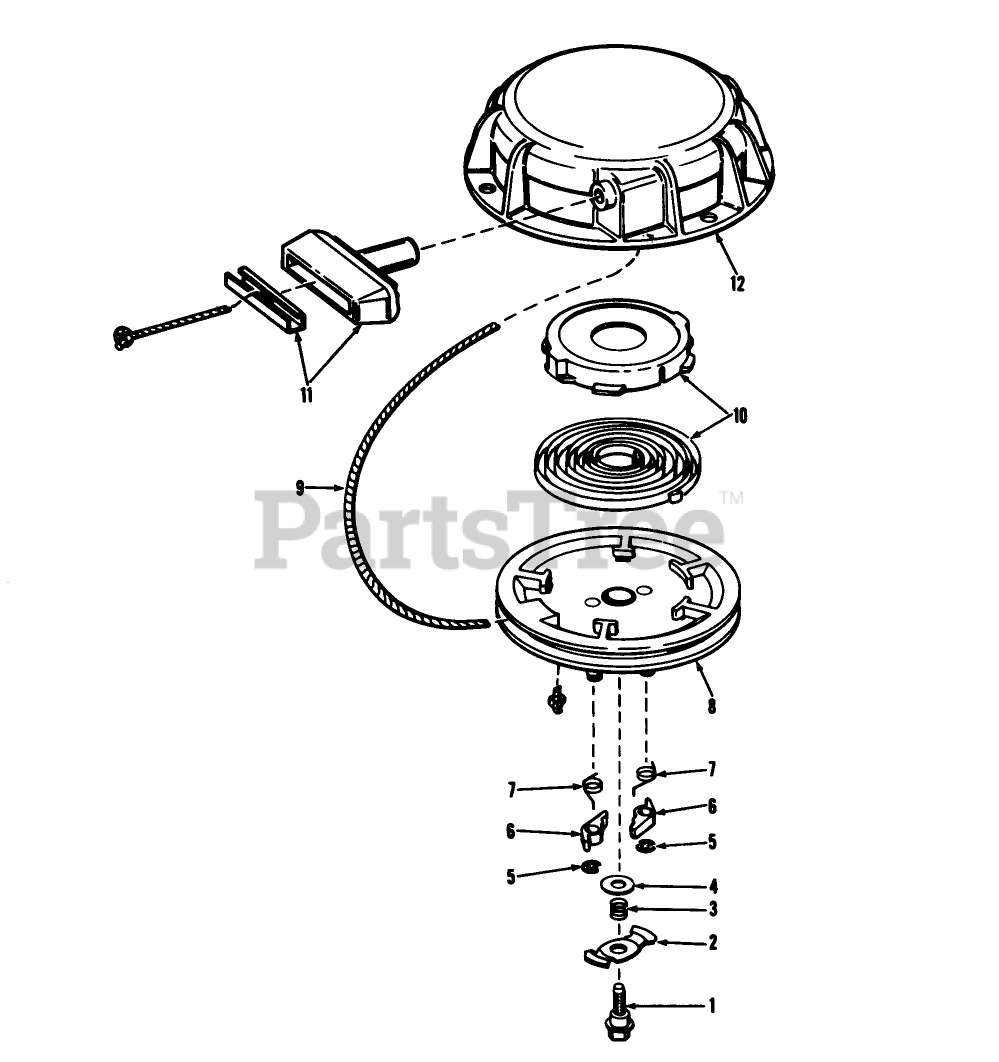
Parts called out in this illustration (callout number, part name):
1	Screw, Center
2	Cam, Dog
3	Spring, Brake
4	Washer, Brake
5	Ring, Retainer
7	Spring, Dog
8	Pulley
9	Rope-Starter
10	Spring Keeper Assy.
11	Assy., Starter
12	Housing Assy., Starter
